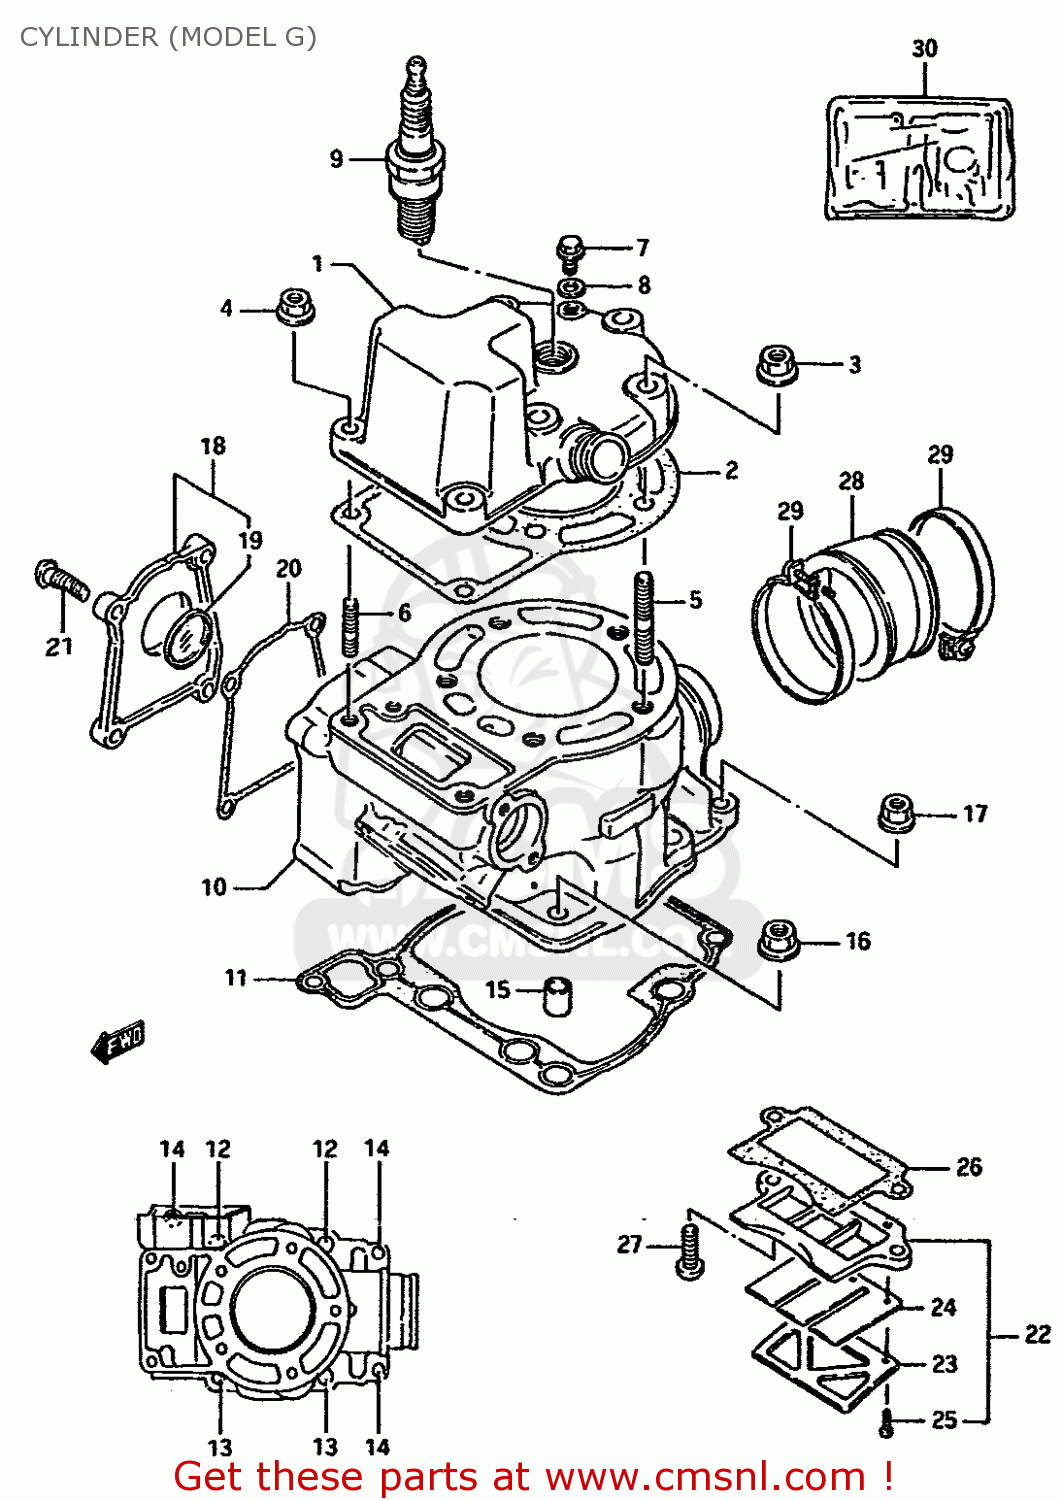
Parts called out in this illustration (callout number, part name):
1	HEAD,CYLINDER
2	GASKET,CYLINDER HEAD
3	NUT
4	NUT
5	BOLT,STUD
6	BOLT,STUD
7	UNION
8	GASKET(6.2X11X1).2 (NAS)
9	SPARK PLUG
10	CYLINDER
11	GASKET,CYLINDER
12	BOLT,STUD L:25
13	BOLT,STUD
14	BOLT,STUD
15	PIN
16	NUT
17	NUT
18	COVER,CYLINDER
19	LENS
20	GASKET,CYLINDER COVER
21	SCREW
22	VALVE ASSEMBLY,REED
23	STOPPER,REED VALVE
24	VALVE,REED
25	SCREW,REED VALVE
26	GASKET,REED VALVE (MCA)
27	SCREW
28	PIPE,INTAKE
29	CLAMP
30	GASKET SET (MCA)
